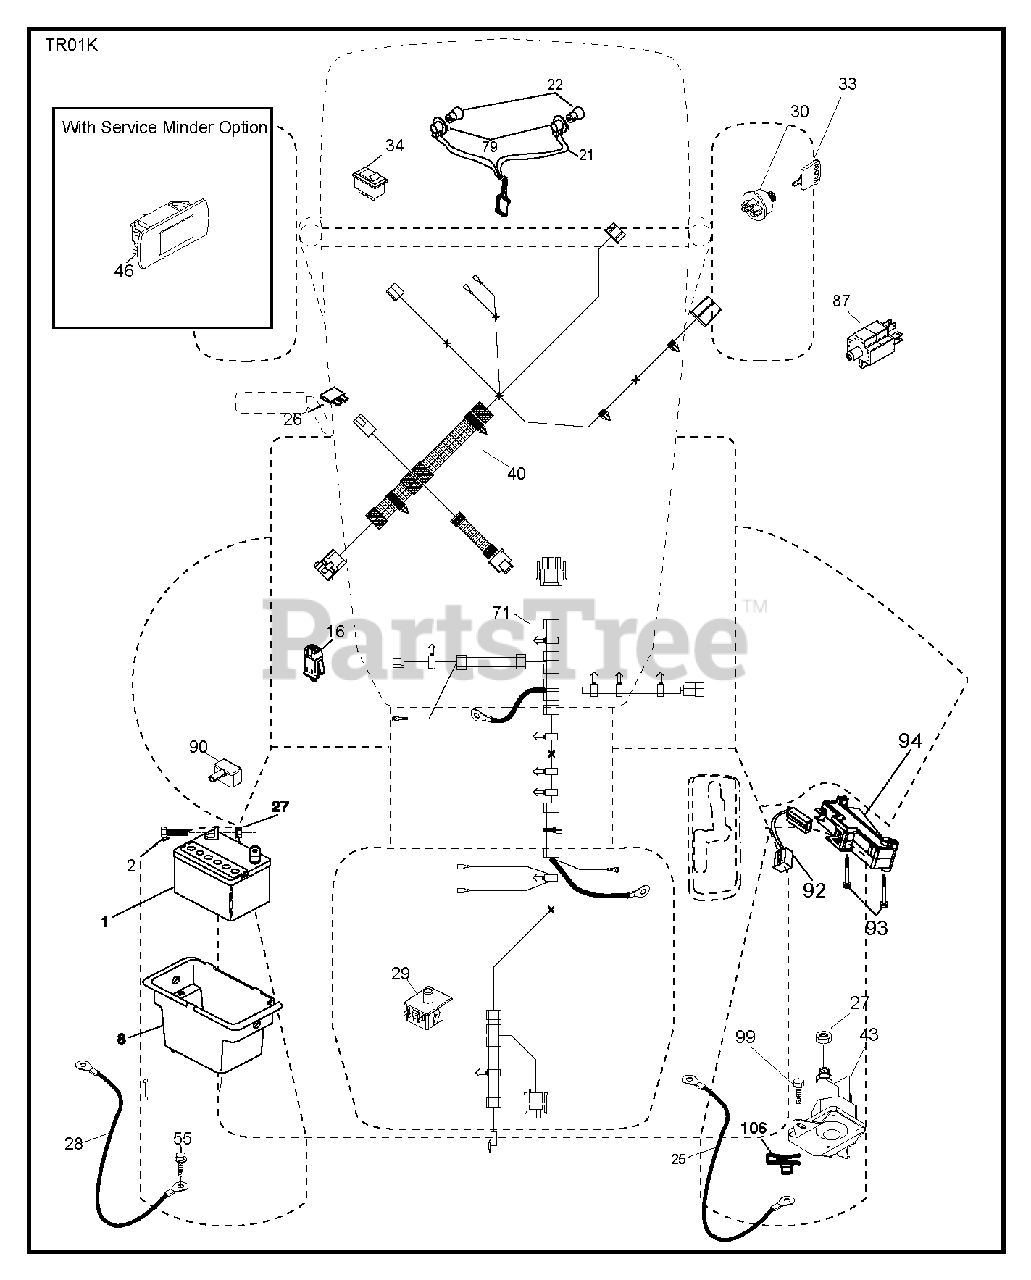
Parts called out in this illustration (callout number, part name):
1	REPL BY 532 12 38-99
8	BOX.BATTERY.MNT.REAR.L
16	SWITCH INTERLOOK PUSH-IN
21	HARNESS.LIGHT W/4152J BULBS
22	LIGHTBULB
25	Positive Battery Cable, Red 8 Ga 17
26	FUSE 20AMP
27	NUT
29	SWITCH.SEAT.DELTA.OPC.
30	SWITCH.IGN.DELTA.W.LGH.ROS
33	KEY.CHAIN.BLISTER.PACK.GEN.INT
34	SWITCH LT
40	Dash Harness, Tex Rear Batt
43	SOLENOID.W/BRASS.PLUNG
55	SCREW 5/16"
71	Harness, Tex Chssis.Rear.Batt
79	BULB HOLDER ASM.
87	SWITCH.INTRLCK.CLUTCH.
90	COVER.TERMINAL.BATTERY
92	HARNESS.PIGTAIL.CONSLE
93	SCREW.PLASTITE
94	MODULE.REVERSE.ROS
99	SCREW HEXWSHR 1/4-20X3/4
106	1/4-20 U NUT
